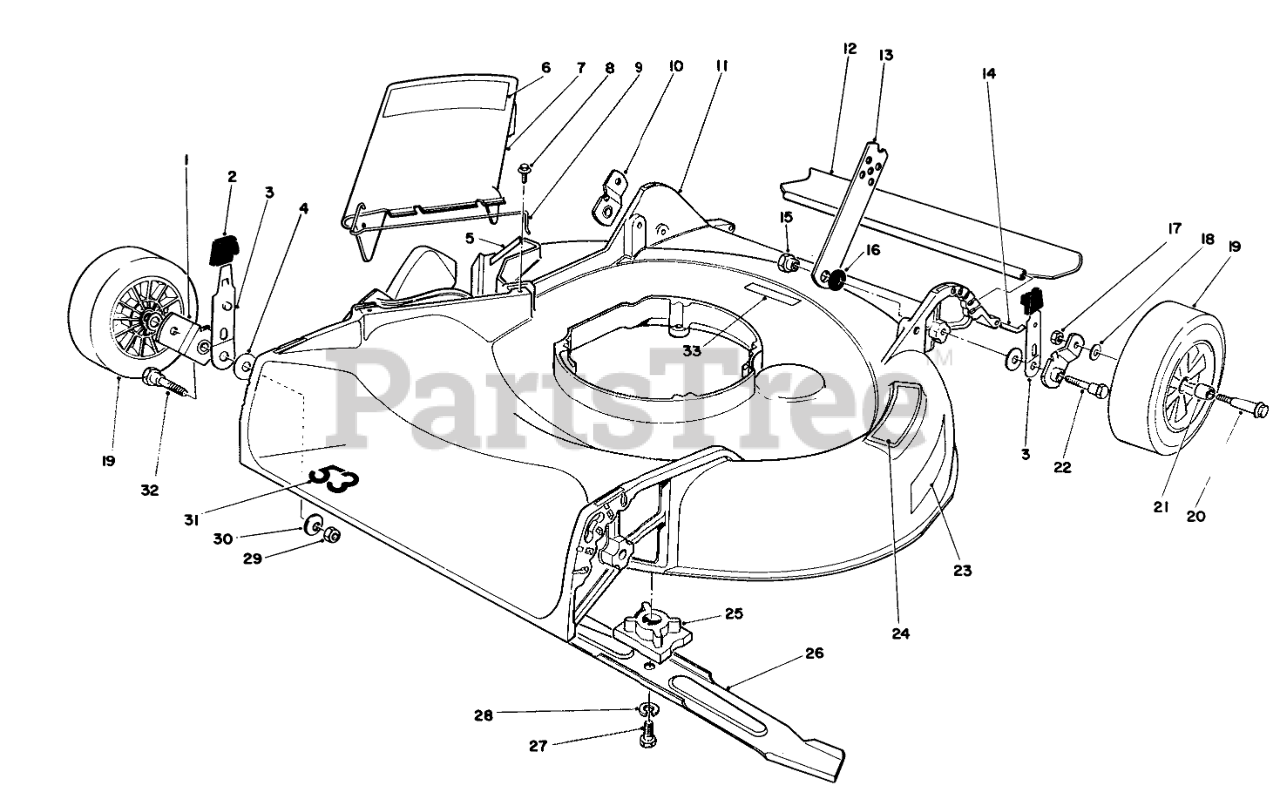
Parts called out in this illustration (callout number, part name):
1	Pivot Arm
2	KNOB-ARM
3	SPRING ARM ASM
4	WASHER-PIVOT
5	DANGER DECAL
6	DECAL - DANGER DEFL
7	Deflector (Incl. Ref. #6)
8	SCREW-HWH
9	SPRING HINGE
10	Pivot Arm
11	HOUSING/DECAL
12	REAR SAFETY SHIELD 21
13	HANDLE LATCH
14	SHIELD ROD
15	HANDLE PIVOT NUT
16	SPACER
17	Nut
18	WASHER
19	Wheel & Tire Assembly (Incl. Ref. #21)
20	BOLT-WHEEL
21	BUSHING
22	PIVOT SCREW
23	Decal Danger
24	DECAL - STEP PAD INT'L
25	BLADE RETAINER
26	Blade
27	SCREW-HH
28	WASHER-LOCK
29	NUT-LOCK, NI
30	WASHER-BELLEVILLE
31	DECAL - 53
32	5/16-18 PIVOT SCREW
33	Decal
